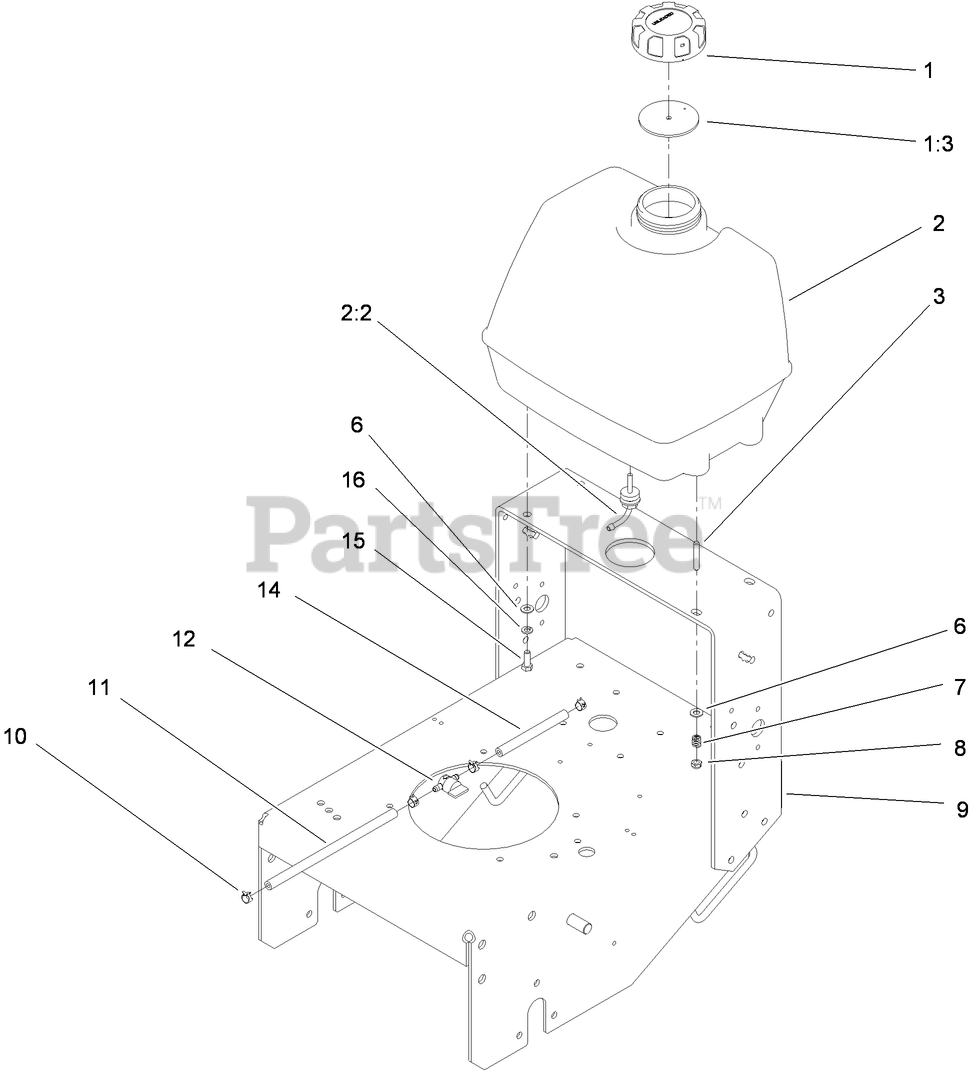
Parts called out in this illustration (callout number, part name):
1	GAS CAP ASM
1:3	GASKET-CAP, GAS
2	FUEL TANK ASM
2:2	FITTING-FUEL, BULKHEAD
3	STUD-THREADED
6	WASHER-PLAIN
7	SPRING-TANK, FUEL
8	NUT-LOCK, NI
9	GEAR FRAME ASM
10	CLAMP-HOSE
11	HOSE-FUEL
12	VALVE-FUEL
14	HOSE-FUEL
15	SCREW-HH
16	WASHER-LOCK
